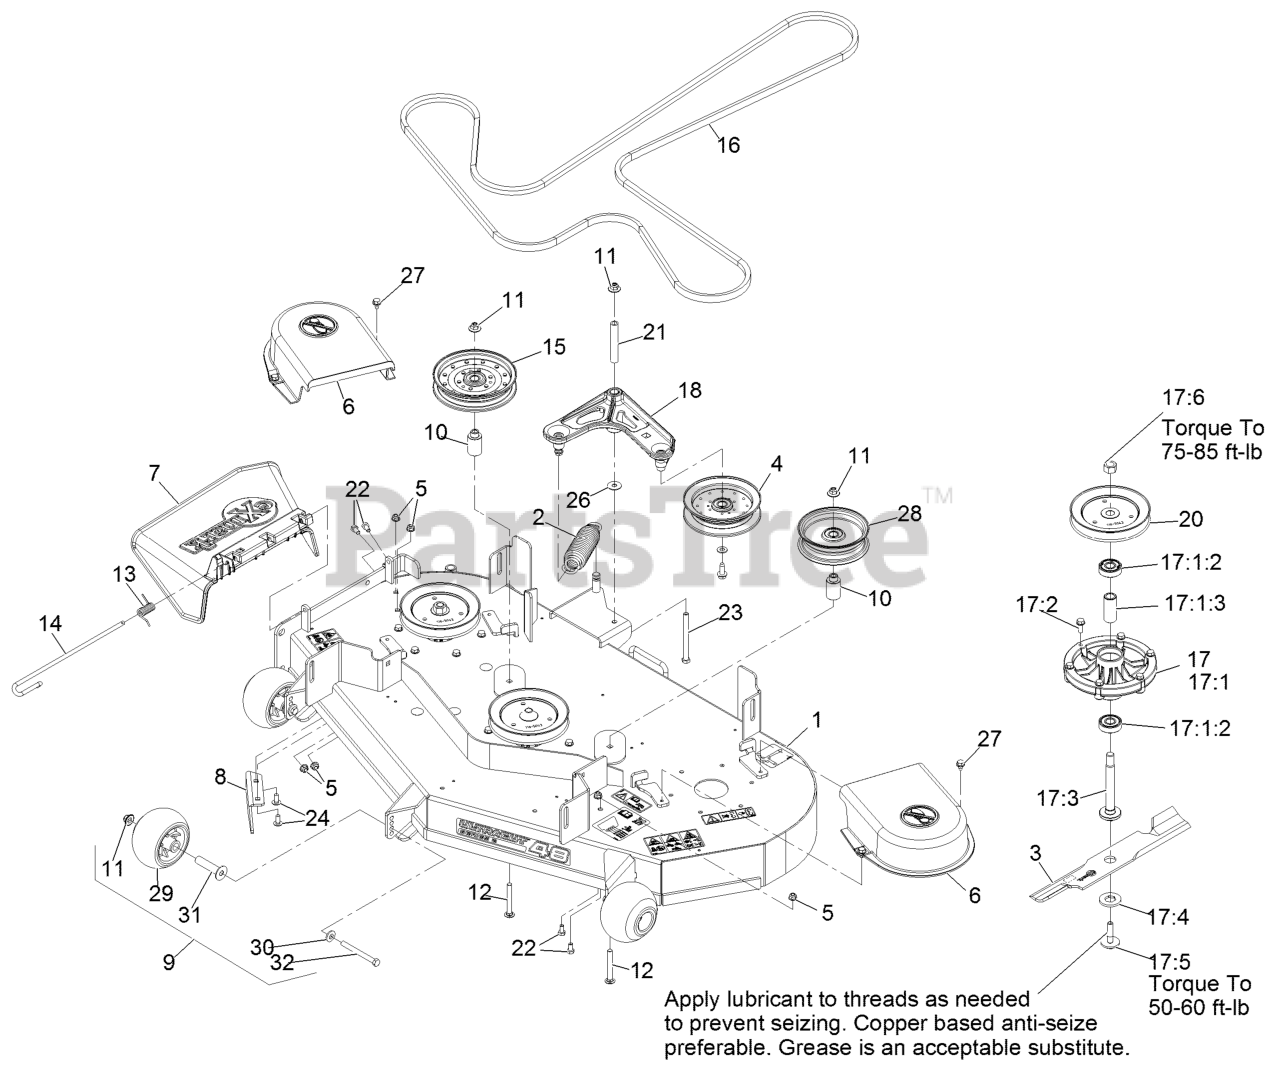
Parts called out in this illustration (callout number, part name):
1	ASM-482 DECK W/DECALS
2	SPRING-EXTENSION
5	NUT-HF, NI
6	SHIELD-BELT
7	CHUTE DEFLECTOR XRK M056
8	BAFFLE-DISCHARGE
9	KIT, ANTI-SCALP ROLLER
10	BUSHING-IDLER
11	Nut-Nyloc 3/8-16 Flg
12	BOLT-CARRIAGE
13	SPRING-TORSION
14	PIN-CHUTE
16	BELT-B154.88
17	CUTTER HOUSING ASM
17:1	HOUSING-CUTTER
17:1:2	BEARING
17:1:3	SPACER-BEARING
17:2	SCREW-TAPTITE
17:3	SPINDLE-HEX PILOT
17:4	WASHER-BLADE DRIVE
17:5	BOLT-BLADE, SEM
17:6	NUT-HEX
18	IDLER ARM ASM
20	SHEAVE,BLADE DRIVE 5.90
21	BUSHING
22	SCREW-HH
23	SCREW-HH
24	SCREW-CARR
28	IDLER-PULLEY, FLAT
29	ROLLER-SCALP, ANTI
30	WASHER-BELLEVILLE
31	AXLE, ROLLER
32	SCREW-HH 3/8-16 X 3 3/4 GR 8
